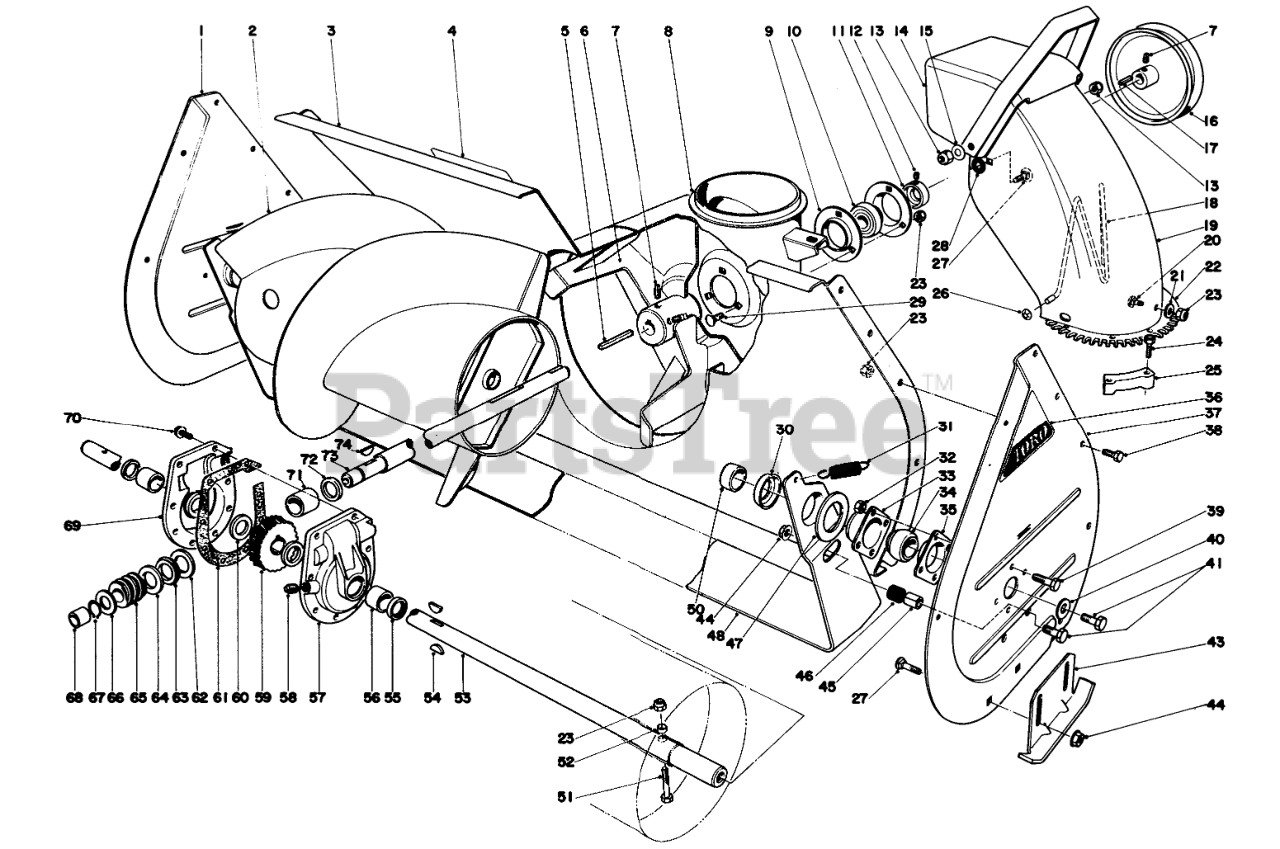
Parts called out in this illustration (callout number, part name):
1	RH AUGER SIDE PLT R
2	RH AUGER ASM - 32"
3	AUGER HSG WA 32" R
4	Decal-Warning
6	IMPELLER ASM
7	SCREW-SET, SQH
8	CHUTE RING
9	BRG FLANGE
10	BALL BRG W/COLLAR
11	EXT LOCKING COLLAR
12	SCREW-HSH
13	NUT-LOCK, CONE
14	Deflector
15	WASHER-BELLEVILLE
16	1/2 X 9.5 DIA PULLEY
17	SQUARE KEY
18	WIRE-CHUTE
19	Upper Chute
20	SCREW-CARR
21	WASHER-PLAIN
22	Screw
23	NUT-LOCK, NI
24	SCREW-SPECIAL
25	RETAINER-CHUTE
26	NUT-PUSH
27	SCREW-CARR
28	WASHER-RUBBER
29	BOLT-CARR
30	Positioner-Scraper
31	SPRING-TENSION
32	NUT-LOCK, CONE
33	BEARING-FLANGE, FRONT
34	BEARING
35	BEARING-FLANGE, REAR
36	AUGER SIDE PLT DECAL
37	LH AUGER SIDE PLT R
38	SCREW-HH
39	SCREW-HH
40	WASHER
41	SCREW-HH
43	AUGER SKID WA R
44	NUT-HF
45	SCRAPER STOP SPACER
46	SCRAPER STOP CUSHION
47	SCRAPER BLADE SPACER
48	SCRAPER BLADE 32" R
50	AUGER SPACER
51	Auger Bolt
52	SPACER-HUB, AUGER
53	32 AUGER SHAFT
54	KEY-WOODRUFF
55	SEAL-OIL
56	BUSHING
57	Gear Case L.H.(Incl. Ref. #55-56)
58	PLUG-PIPE, SQH
59	GEAR-WORM, 27T
60	WASHER-THRUST
61	asket
62	WASHER-THRUST
63	BEARING-THRUST
64	THRUST-WASHER
66	WASHER-THRUST
67	Ring-Snap
68	BUSHING
69	Gear Case R.H.(Incl. Ref. #55-56)
70	SCREW-TAPTITE
71	BUSHING-SPECIAL
72	RING-QUAD
73	SHAFT-IMPELLER
74	KEY-WOODRUFF
